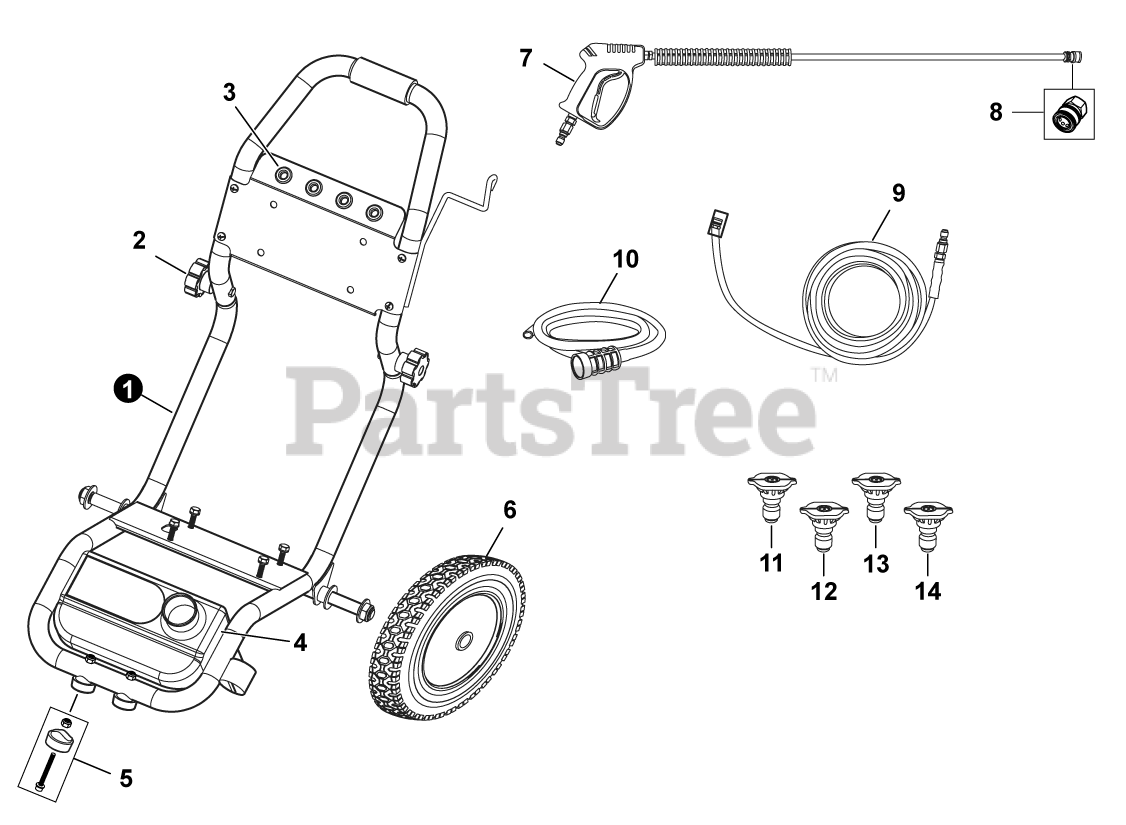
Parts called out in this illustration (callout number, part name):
1	FRAME PW-3100
2	KNOB, HANDLE PW-1300 & PW-4200
3	GROMMET, NOZZLE PW-1300 & PW-4200
4	SOAP TANK
5	KIT, RUBBER FOOT
6	WHEELS, PW-3100 AND PW-4200
7	GUN & WAND ASSY.
8	1/4" FNPT Q/C
9	HOSE, 25'
10	HOSE, SOAP
11	NOZZLE, SOAP
12	NOZZLE, #3.0 40 DEGREE
13	NOZZLE, #3.0 15 DEGREE
14	NOZZLE, #3.0 0 DEGREE
15	NOZZLE, #2.7 WHITE
16	NOZZLE, #2.7 YELLOW
17	NOZZLE, #2.7 RED
